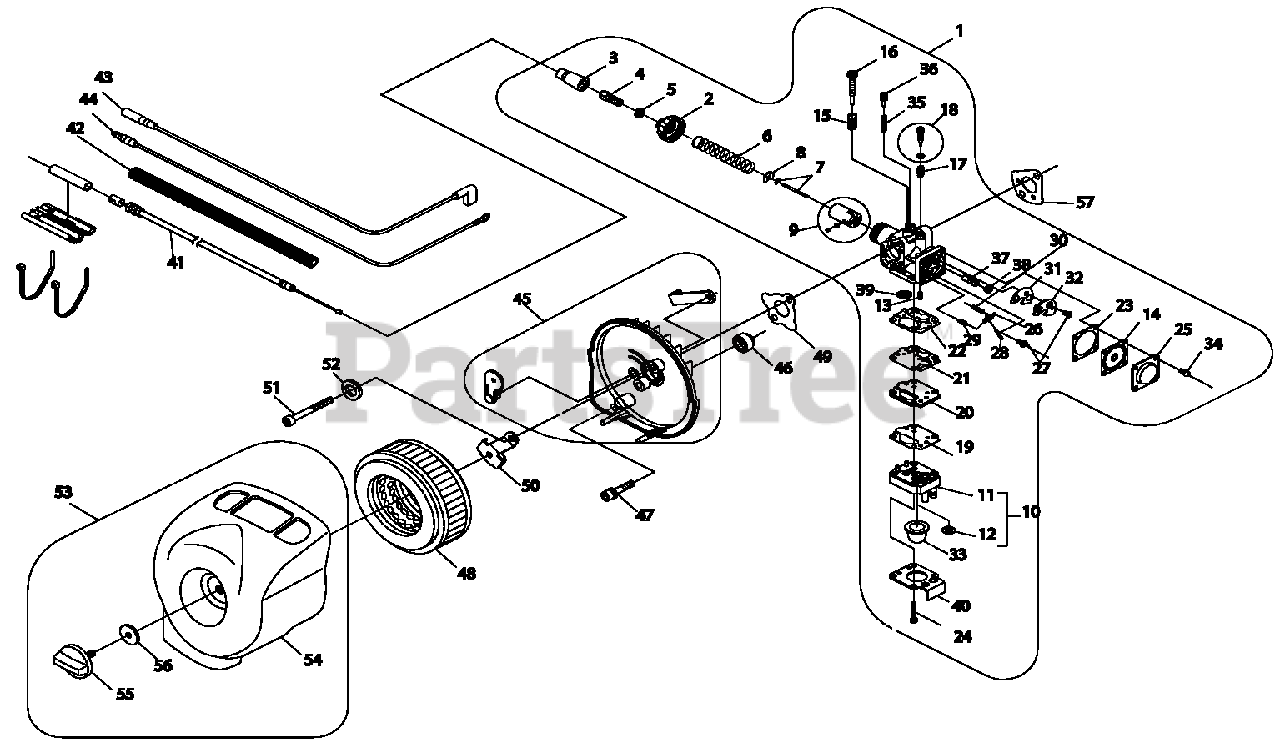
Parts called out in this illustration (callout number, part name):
1	CARBURETOR ASSY
2	COVER, TOP
3	GROMMET
4	ADJUSTER, CABLE
5	NUT, LOCK
6	SPRING, THROTTLE
7	NEEDLE, JET
8	WASHER
9	VALVE, THROTTLE
10	COVER ASSY, PUMP
11	COVER, PUMP
12	VALVE
13	SPRING, COIL
14	DIAPHRAGM, METERING
15	SPRING
16	SCREW, MAIN ADJUST
17	SPRING
18	SCREW, IDLE ADJUST
19	GASKET, FUEL PUMP
20	PLATE, FUEL PUMP
21	DIAPHRAGM, FUEL PUMP
22	GASKET, FUEL PUMP
23	GASKET, DIAPHRAGM
24	SCREW
25	COVER, DIAPHRAGM
26	LEVER, METERING
27	SCREW M3×8
28	PIN, METERING LEVER
29	VALVE, INLET NEEDLE
30	SPRING
31	PACKING
32	PLATE
33	BULB, PURGE
34	SCREW M3×8
35	SPRING
36	SCREW, SLOW AIR
37	NEEDLE, JET
38	HOLDER, MAIN JET
39	SCREEN, FUEL INLET
40	PLATE, PUMP
41	CABLE, THROTTLE
42	TUBE, FLEXIBLE
43	WIRE, LEAD
44	WIRE, LEAD
45	CASE ASSY, AIR FILTER
46	INSULATOR
47	BOLT M5×40
48	FILTER, AIR
49	GASKET, INTAKE
50	PLATE, PREVENT
51	BOLT 5×75
52	WASHER, SPRING 5
53	COVER ASSY, AIR FILTER
54	COVER, AIR FILTER
55	THUMBSCREW
56	WASHER
57	GASKET, INTAKE
